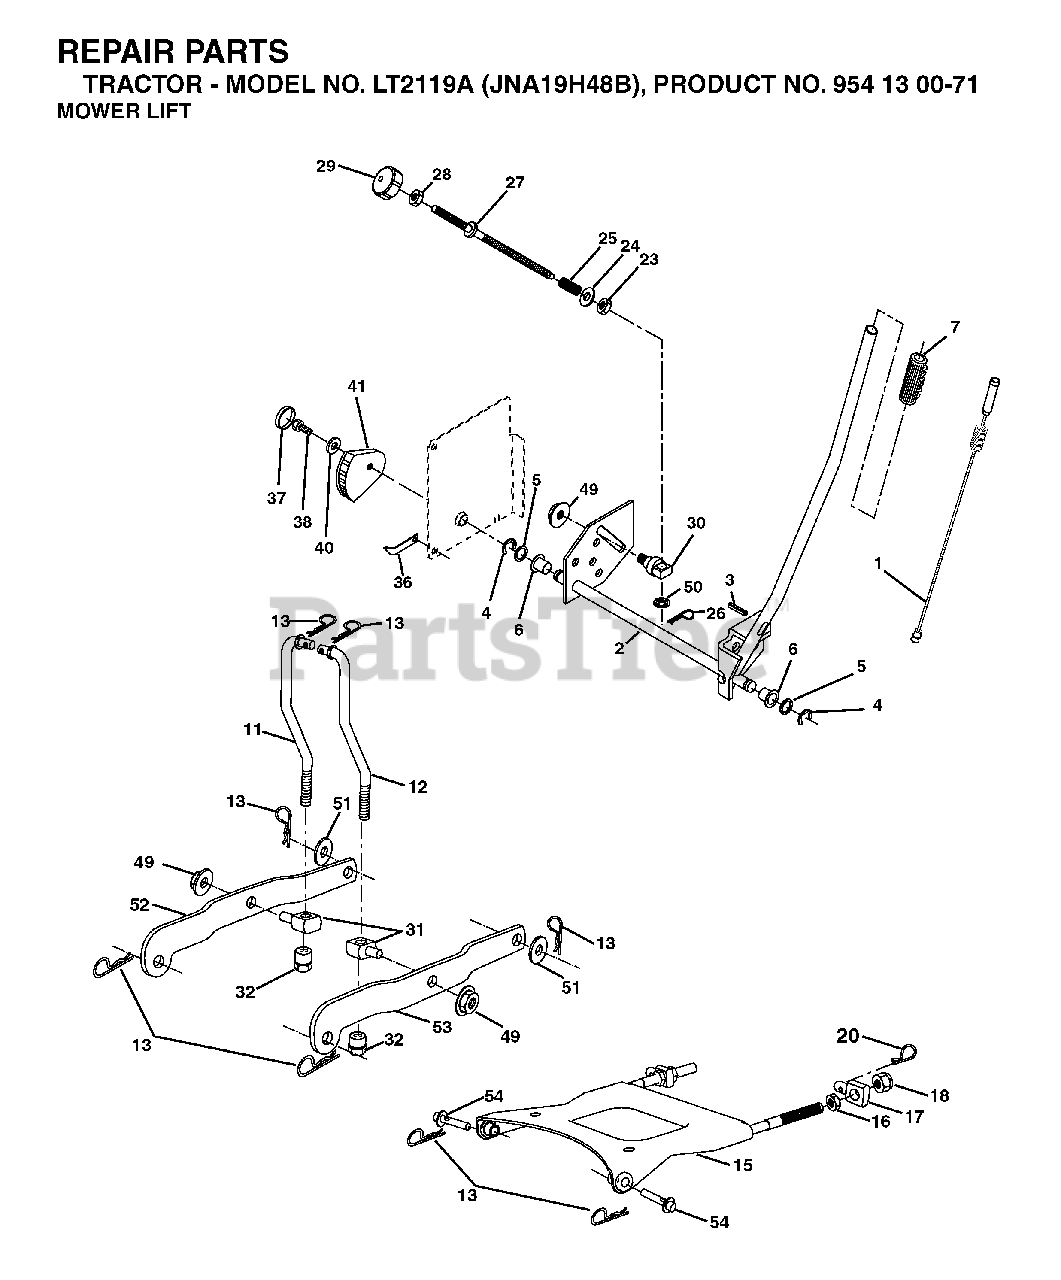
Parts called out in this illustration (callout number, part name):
1	WIRE ASM INNER W/ PLUNGER LT
2	SHAFT ASM R HANDLE
3	PIN GROOVE
4	RETAINING RING LT
6	BEARING.NYLON
7	GRIP HANDLE
8	PLUNGER BUT KIT
11	LIFT LINK LH
12	LIFT LINK RH
13	RETAINER-SPRNG RB
15	PLATE ASM SUSP FRONT
16	NUT
18	NUT
20	SPRING RETAINER
25	SPRING**
26	RETAINER CLIP
27	ROD ADJ LIFT
28	NUT
29	KNOB INF 3/8-16
32	NUT, LIFT LINK 7/16-20
36	POINTER, HEIGHT INDICATOR
37	PLUG,HOLE
38	SCREW 5/16-18X1
41	IND. HEIGHT STLT
49	NUT
50	NUT PUSH M
52	ARM SUSP. REAR LH
53	ARM SUSP REAR RH
54	PIN, FLANGE
